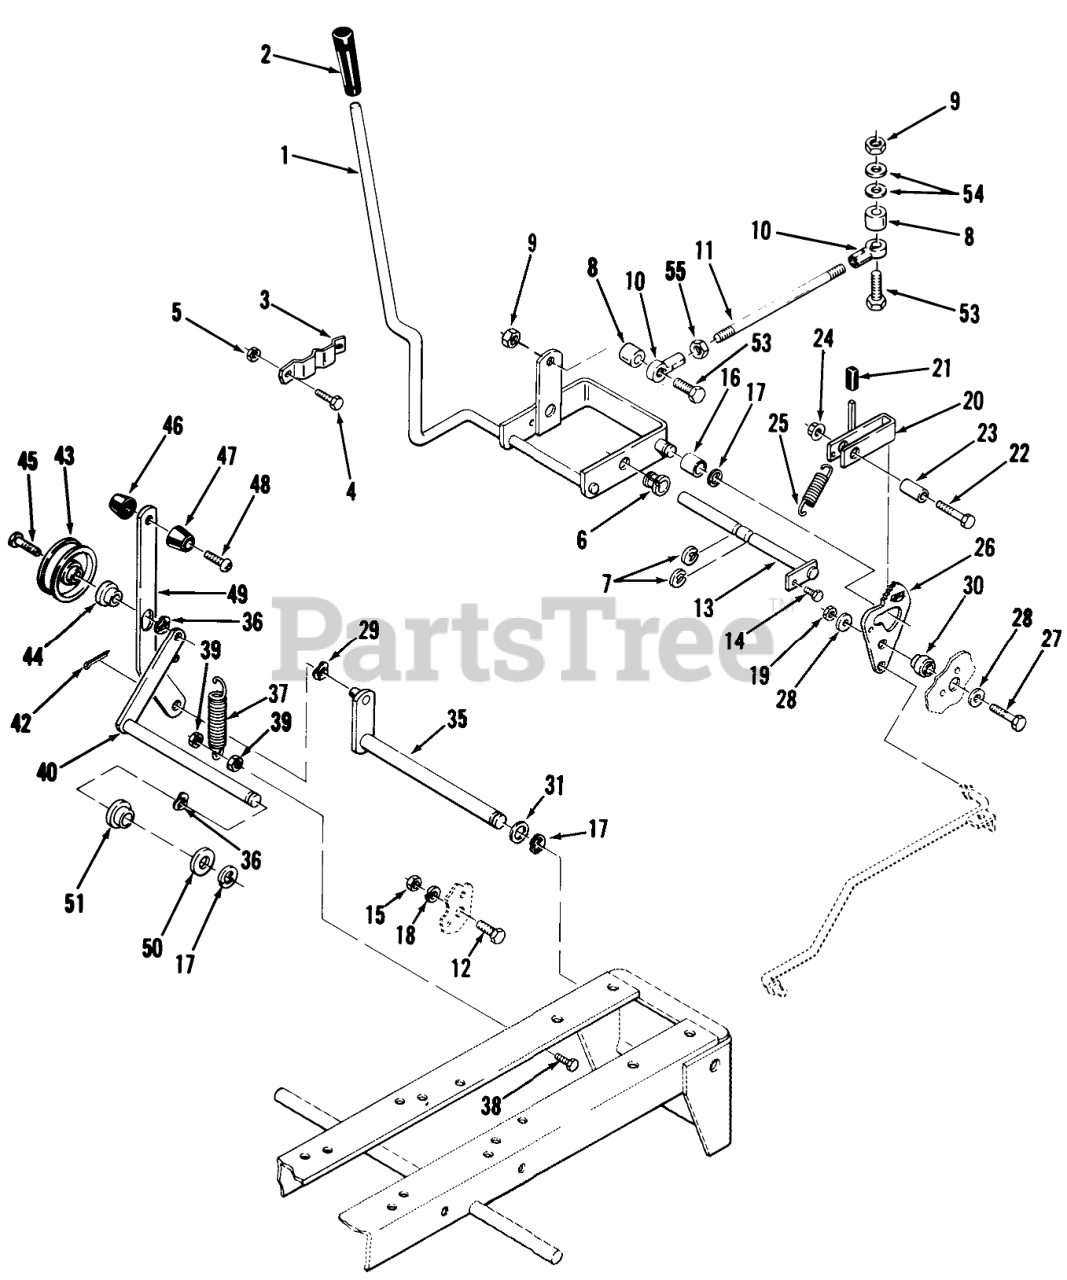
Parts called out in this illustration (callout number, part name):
1	Motion Control Lever
2	KNOB
3	Detent-Motion Control Lever
4	H H C S
5	Nut
6	NYLINER BUSHING
7	E Ring
8	Spacer
9	Nut
10	Rod End
11	ROD-CONTROL
12	Bolt
13	ASSY-ROD CAM PIVOT
14	SCREW
15	Nut
16	BEARING-CAM RETURN
17	E Ring
18	LOCKWASHER
19	Nut
20	PAWL HDL ASSY B
21	VALVE LEVER GRIP
22	BOLT
23	SPACER
24	LOCKNUT-FLANGE
25	Spring
26	Cam Plate
27	Bolt
28	Washer
29	WASHER-WAVE
30	Spacer
31	Washer
35	ASSY-BRAKE LEVER
36	WASHER-WAVE
37	SPRING-EXTENSION
38	Bolt
39	Nut
40	ASSY-ARM/ROD WA
42	Cotter Pin
43	Idler Pulley
44	SPACER-BRAKE LINK
45	BOLT-SPECIAL HEX
46	KNOB
47	KNOB
48	BOLT-4
49	Handle
50	Washer
51	BUSHING-FLANGED
53	Bolt 1/4-20 X 1 1/2
55	Jam Nut 1/4-28
